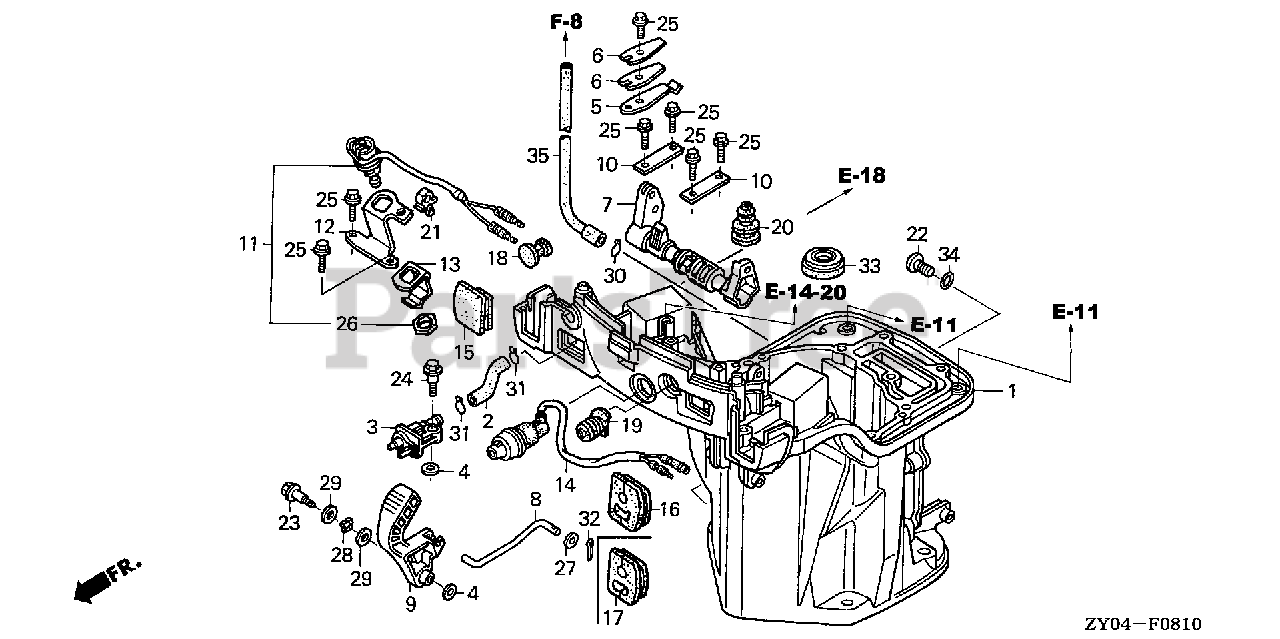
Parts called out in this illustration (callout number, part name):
2	TUBE A, FUEL
3	CONNECTOR ASSY., FUEL (B)
4	WASHER, PIVOT
5	SPRING, CLICK
6	SPRING, CLICK ASSIST
7	SHAFT, SHIFT
9	LEVER, SHIFT
10	PLATE, SHIFT SHAFT
14	LAMP ASSY., INDICATOR
15	GROMMET A, OIL CASE
16	GROMMET B, OIL CASE
19	GROMMET D, OIL CASE
20	GROMMET E, OIL CASE
22	BOLT, OIL CHECK
23	BOLT, REVERSE LOCK
24	BOLT, SPECIAL (6X22) (CT200)
25	BOLT, FLANGE (5X12) (CT200)
27	WASHER, PLAIN (5MM)
28	WASHER, WAVE (10MM)
29	WASHER, PLAIN (9MM)
30	CLIP, TUBE (B10)
31	CLIP, TUBE (B12)
32	PIN, SPLIT (2.0)
33	SEAL, WATER (15X28X6)
34	O-RING (5.5X1.5)
35	TUBE, WATER CHECK
